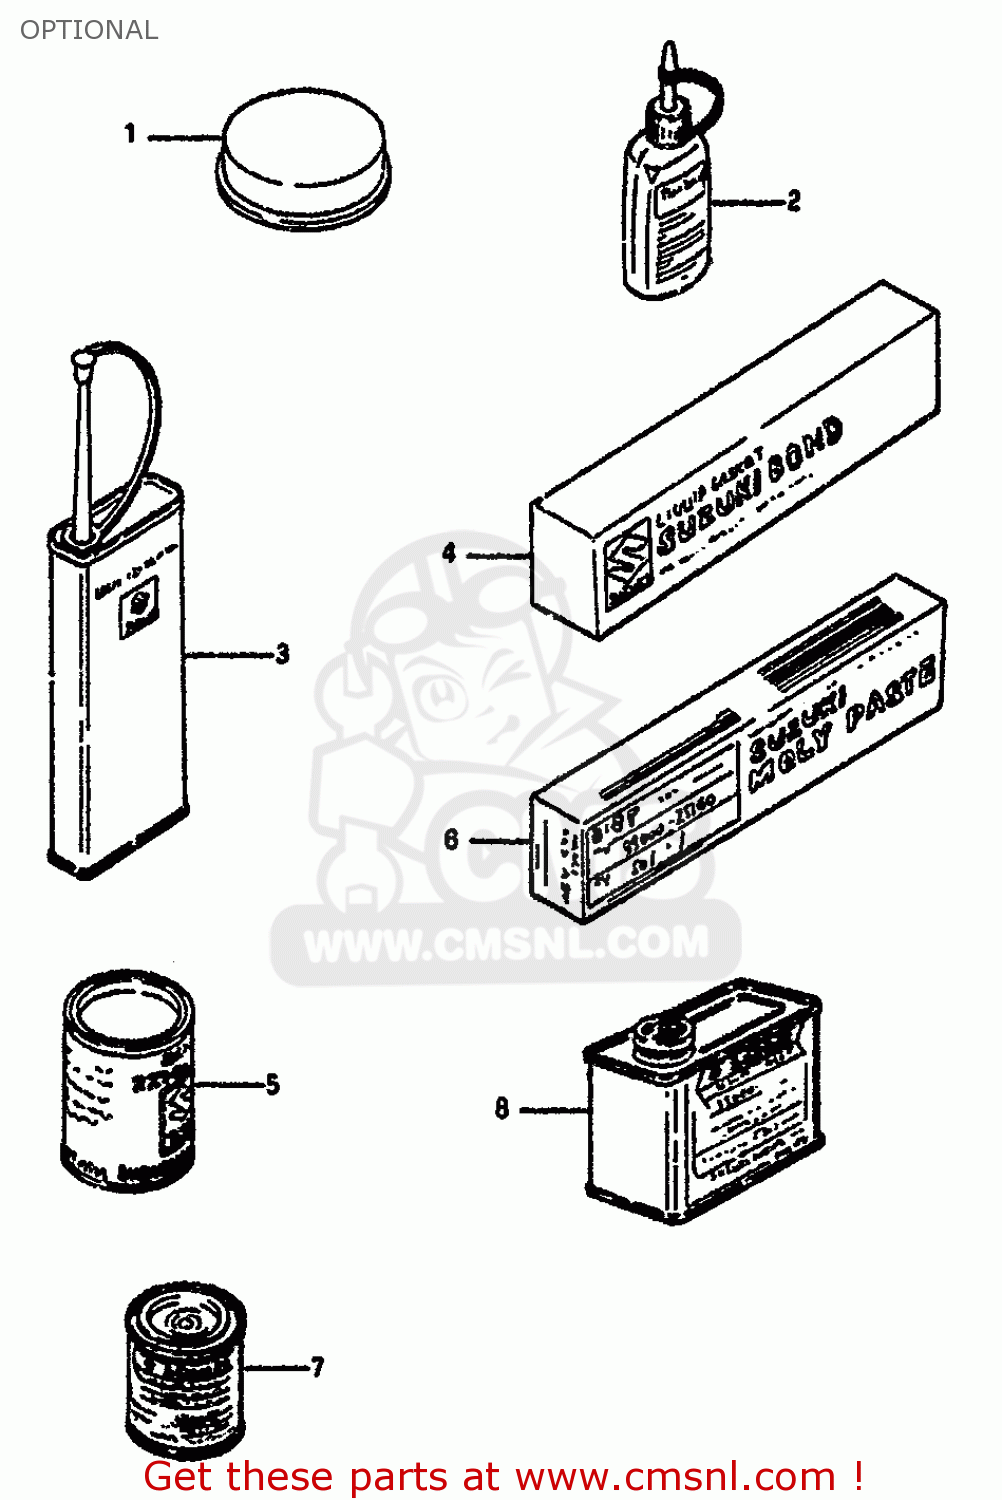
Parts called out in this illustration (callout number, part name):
1	GREASE,PBC FOR BRK PAD 20G
2	THREAD LOCK NO.1342
3	THREAD LOCK NO.1401 CLEAR 200G
4	LIQUID GSKT NO.1207B 100G BLK
5	GREASE(C)EP2 LITHIUM 150G
6	SUZUKI MOLY PASTE
7	PAINT,BLACK
8	PAINT (BLACK)
